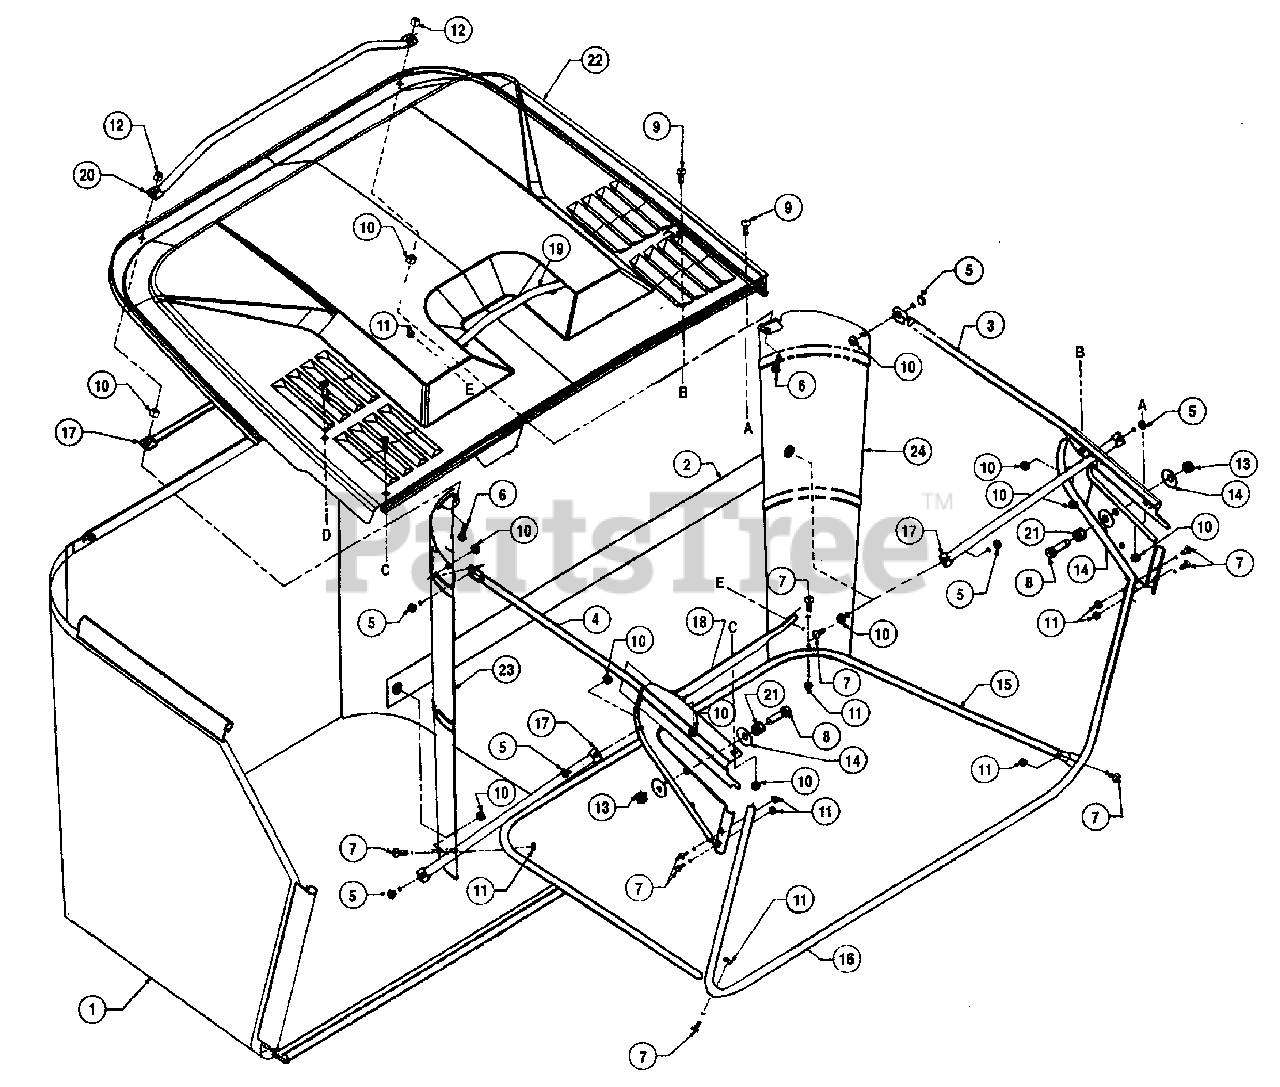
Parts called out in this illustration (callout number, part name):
1	Grass Bag
2	Strap Ass'y.
3	Grass Catcher Support Brkt.-L.H.
6	Hex Bolt 1/4-20 x 1" Lg.
7	Hex Bolt #10-24 x .88" Lg.
8	Hex Bolt 3/8-16 x 1.25" Lg.
9	Pan Hd. Scr. 1/4-20 x .75" Lg.
10	Hex Sems Nut 1/4-20 Thd.
11	Hex Sems Nut #10-24 Thd.
12	Hex Ins. L-Nut 1/4-20 Thd.
13	Hex Nut 3/8-16 Thd. (Gr. 5)
14	Bell-Wash. .39" I.D. x 1.13" O.D.
